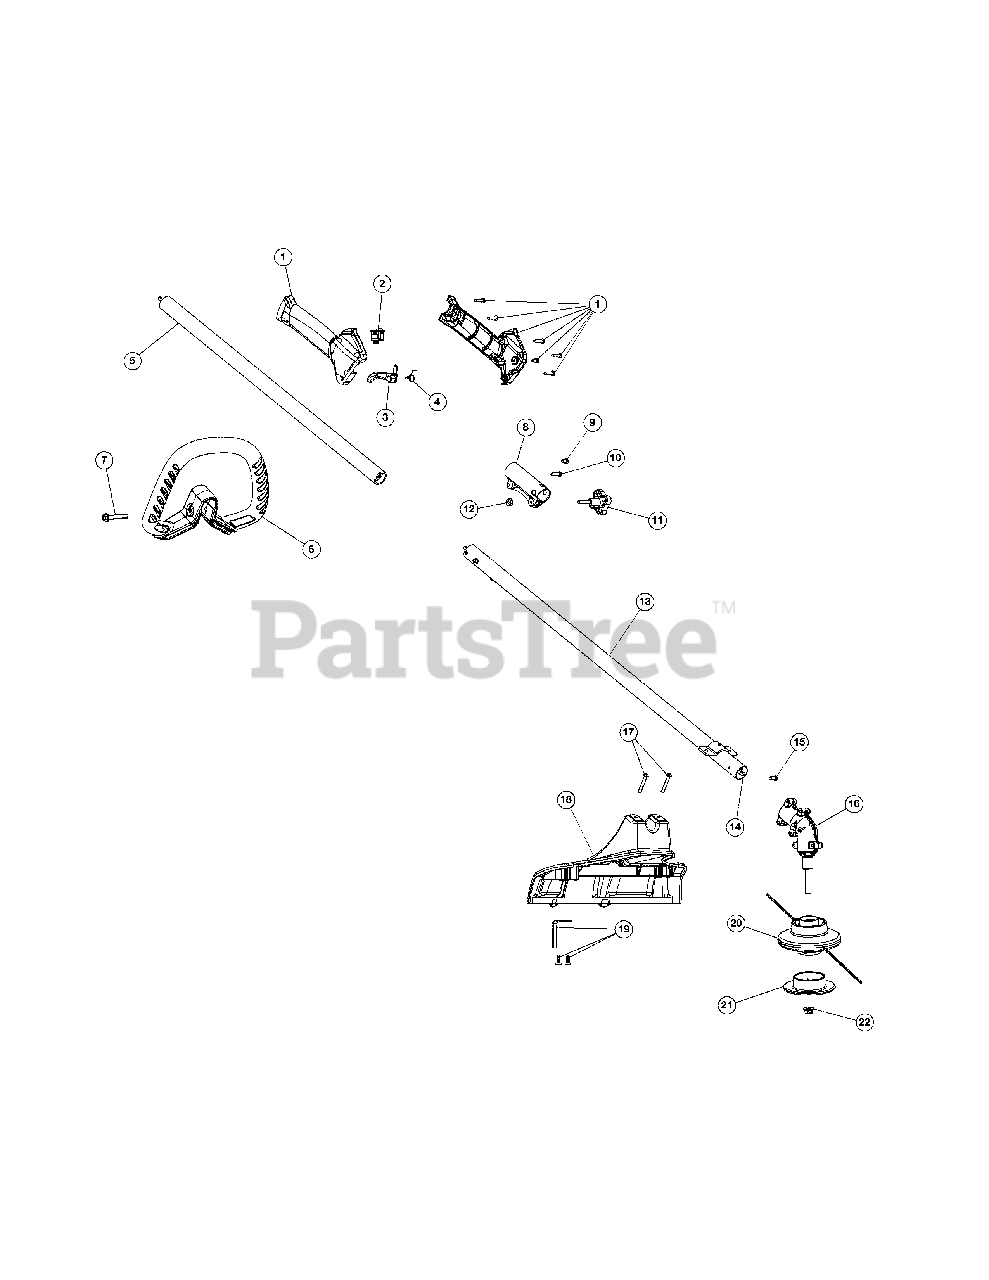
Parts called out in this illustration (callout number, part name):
1	Throttle Housing Assembly (Incl. 2-4)
3	Throttle Trigger
4	Throttle Trigger Spring
5	Upper Shaft Housing Assembly
6	D-Handle (Incl. 7)
7	D-Handle Hardware
8	Split Boom Coupler (Incl. 9-12)
9	Anti-Rotation Screw
11	Adjustment Knob
12	Knob Retainer Nut
13	Lower Shaft Housing Assembly
14	Lower Flexible Drive Shaft
15	Anti-Rotation Screw
16	Gear Box Assembly (Incl. 15 & 20-22)
17	Shield Mounting Screws
18	Shield Assembly (Incl. 17 & 19)
19	Blade Assembly
20	Cutting Head Assembly (Incl. 21 & 22)
21	Glide Cap
22	Lock Nut
